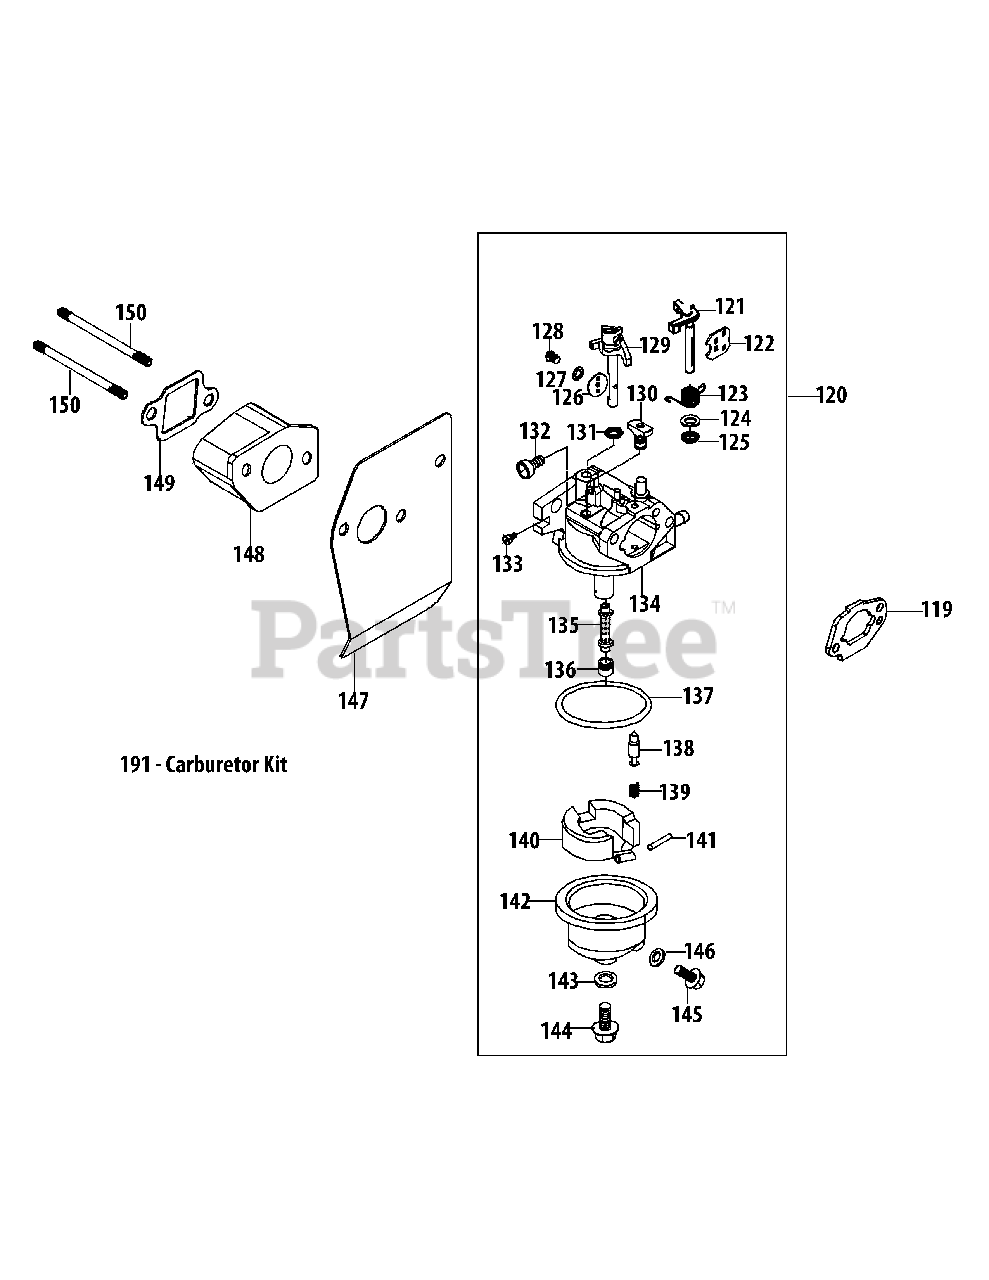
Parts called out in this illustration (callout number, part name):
119	Carburetor Gasket Plate
120	Carburetor Assembly
121	Choke Shaft
122	Choke Plate
123	Choke Return Spring
124	Choke Shaft Washer
125	Choke Shaft Fiber O-Ring
126	Throttle Plate
127	Throttle Plate Lock Washer
128	Screw M3X5 Throttle Plate
129	Throttle Shaft
130	Idle Jet Assembly
131	Throttle Shaft Fiber O-Ring
132	Idle Speed Adjusting Screw
133	Idle Mixture Screw
134	Carburetor Body
135	Emulsion Tube
136	Main Jet
137	Fuel Bowl O-Ring
138	Needle Valve
139	Needle Valve Spring
140	Float
141	Float Pin
142	Fuel Bowl
143	Fuel Bowl Gasket
144	Fuel Bowl Mounting Bolt
145	Fuel Drain Plug
146	Fuel Drain Plug Gasket
147	Carburetor Gasket
148	Carburetor Insulator
149	Carburetor Insulator Gasket
150	Carb Stud M6X92
191	Carburetor Repair Kit - Major
